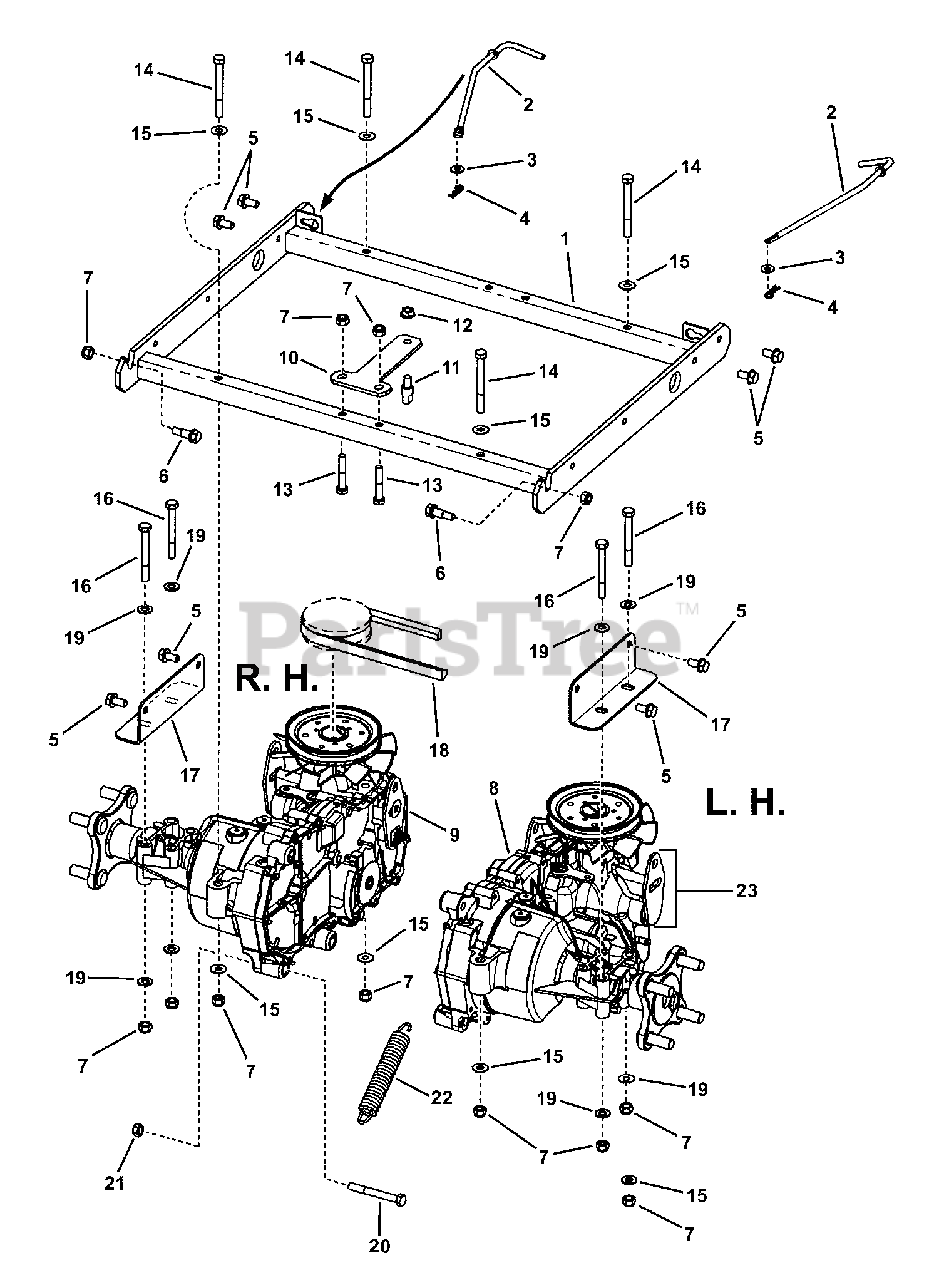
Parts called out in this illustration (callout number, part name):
1	WELDMENT, Transaxle Support
2	ROD, Roll Release
3	WASHER, .28 x .63 x .06 Flat, GR 5
4	HAIR PIN, 1-1/8"
5	SCREW, 5/16-18 x 5/8" Hex Washer Self-Tap, GR 2
6	SHOULDER BOLT, 5/16-18
7	NUT, 5/16-18 Hex Nyloc
8	TRANSAXLE, LH RZT
9	TRANSAXLE, RH RZT
10	BRACKET, Anti-Rotation
11	PIN, Anti-Rotation, RZT Clutch
12	NUT, 5/16-18 Hex Flange Lock, GR 5
13	SCREW, 5/16-18 x 1-3/4" Hex Head Cap, GR 5, YZ
14	SCREW, 5/16-18 x 3" Hex Head Cap, GR 5, YZ
15	SHIM WASHER, 5/16" I.D.
16	SCREW 5/16-18 x 2-3/4" Hex Head Cap, GR 5, YZ
17	BRACKET, Transaxle Support
18	V-BELT, HA Sect. (wrapped) 58.00 effective length
19	WASHER, .34 x .69 x .08 Flat
20	SCREW, 7/16-20 x 2-1/2" Hex Head Cap, GR 5 (Special Head)
21	NUT, 7/16-20 Hex Center Lock Jam, GR 5 or B
22	SPRING, Extention, .562 OD x 4.250 long x .049 Wire B
23	ARM, Control Kit
